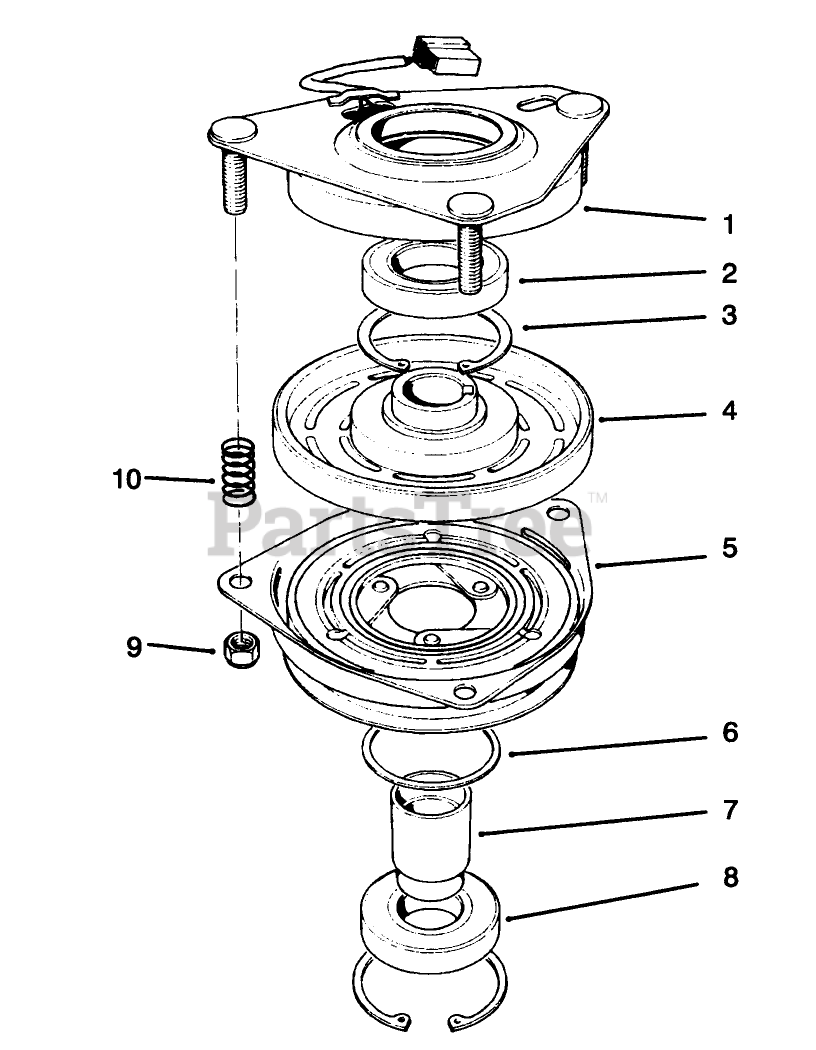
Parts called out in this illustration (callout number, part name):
1	FIELD BEARING ASM
2	BEARING-FIELD
3	RING-RETAINING
4	FIELD COIL/ROTOR BEARING ASM
6	SPACER-BEARING, PULLEY
7	COLLAR-BEARING
9	NUT-HEX
10	SPRING
